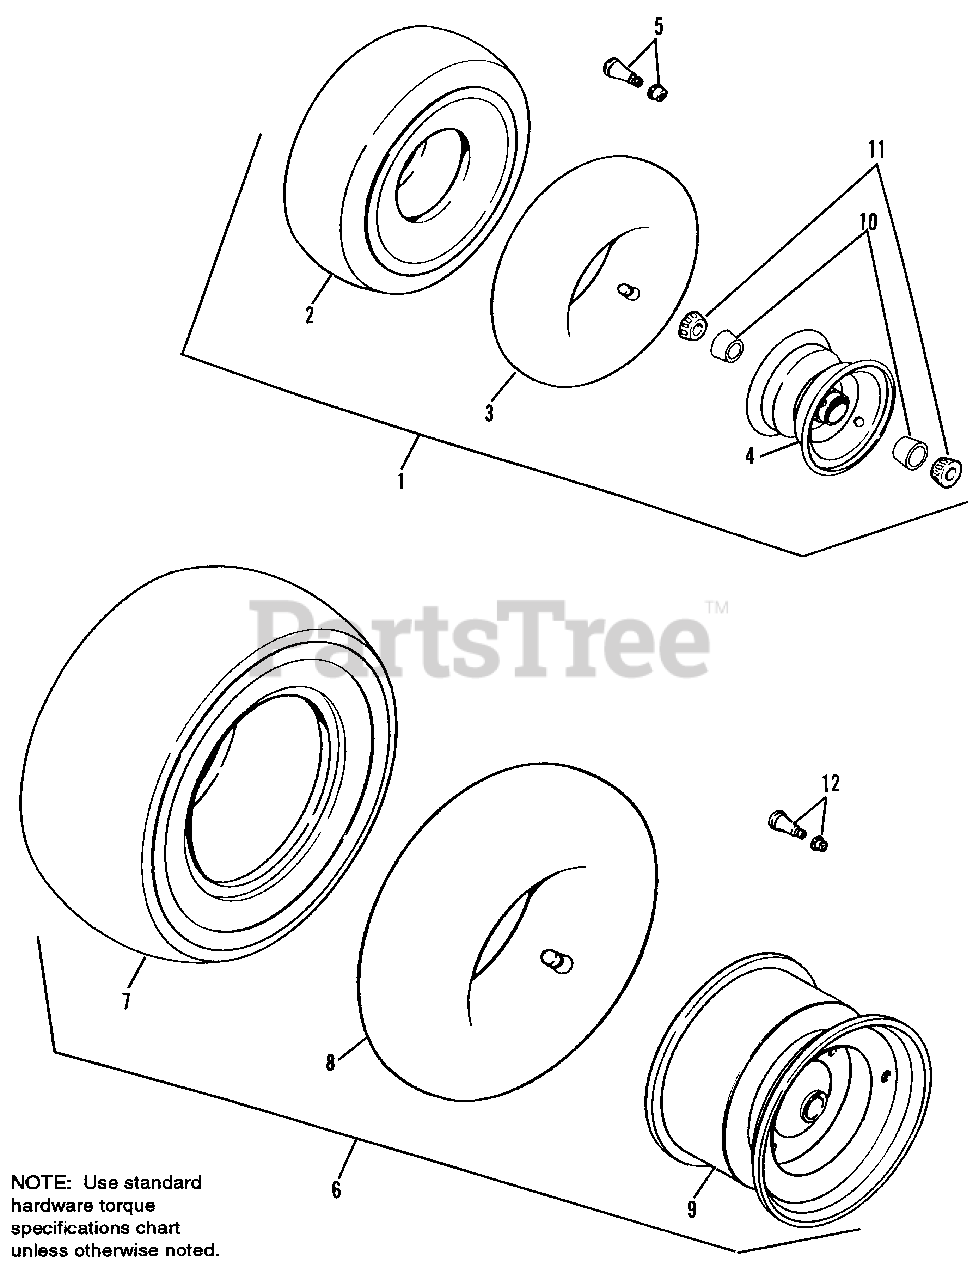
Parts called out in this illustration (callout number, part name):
1	FRONT WHEEL & TIRE ASSY., 16 x 6.50-8, Beige (Incl. Ref. Nos. 2, 3, 4, 5, 10 & 11)
1	FRONT WHEEL & TIRE ASSY., 16 x 6.50-8, Metallic Gray (Incl. Ref. Nos. 2, 3, 4, 5, 10 & 11)
1	FRONT WHEEL & TIRE ASSY., 16 x 6.50-8, Beige (Incl.Ref.Nos. 2, 3, 4, 5, 10 & 11)
1	FRONT WHEEL & TIRE ASSY. (16 x 6.50-8), Silver (Incl. Ref. Nos. 2, 3, 4, 5, 10 & 11)
2	TIRE, Dico, 16 x 6.50-8
2	TIRE, Carlisle, 16 x 6.50-8
3	TUBE, 16 X 6.50-8, (Service only, see note below.)
3	TUBE, 16 X 6.50-8 (Service only, see note below.)
4	WHEEL ASSY. (Incl. Ref. No. 10), Beige
4	WHEEL ASSY. (Incl. Ref. No. 10), Silver
4	WHEEL ASSY., Beige (Incl. Ref. No.10)
4	WHEEL ASSY., Silver (Incl. Ref. No.10)
5	VALVE STEM & CAP
6	REAR WHEEL & TIRE ASSY., 23 x 10.5-12, Beige (Incl. Ref. Nos. 7, 8, 9 & 12)
6	REAR WHEEL & TIRE ASSY., 23 x 10.5-12, Metallic Gray (Incl. Ref. Nos. 7, 8, 9 & 12)
6	REAR WHEEL & TIRE ASSY., 23 x 10.5-12, Beige (Incl.Ref.Nos. 7, 8, 9 & 12)
6	REAR WHEEL & TIRE ASSY., 23 x 10.5-12, Silver (Incl. Ref. Nos. 7, 8, 9 & 12)
7	TIRE, Dico, 23 x 10.5-12
7	TIRE, Carlisle, 23 x 10.5-12
8	TUBE, (23 x 10.5-12)
8	TUBE, 23 x 10.5-12
9	WHEEL ASSY., Beige
9	WHEEL ASSY., Metallic Gray
9	WHEE LASSY., Silver
10	BEARING CUP
11	BEARING CONE
12	VALVE STEM & CAP
